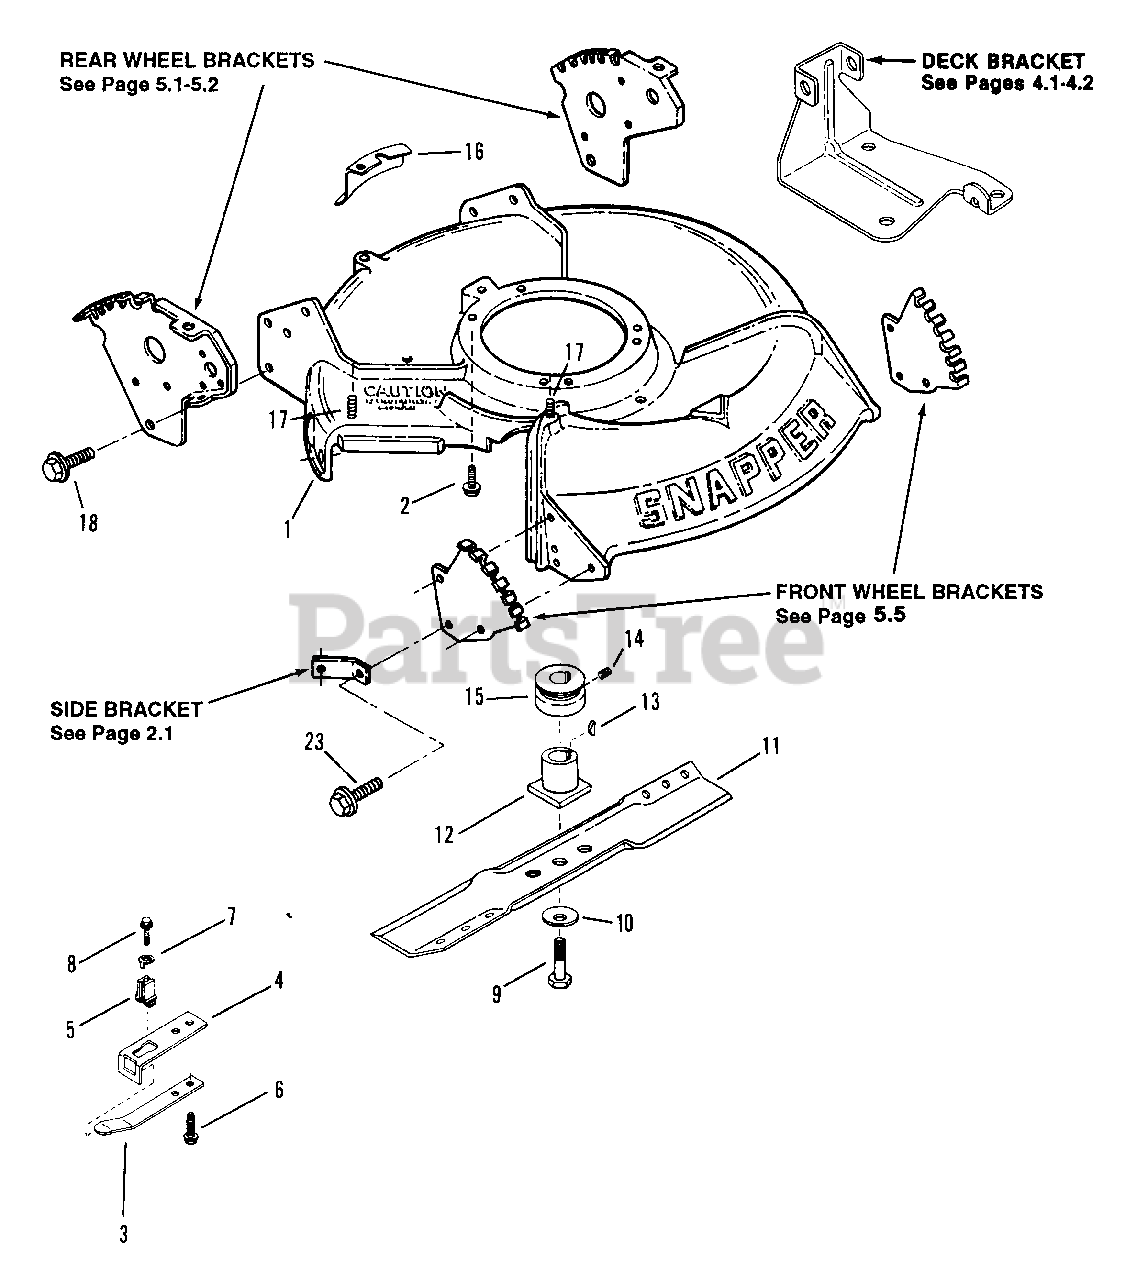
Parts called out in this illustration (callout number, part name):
1	DECK, Mower
2	SCREW, 3/8-16 x 1" Self-Tapping (Engine Mounting)
3	SPRING, Wheel Bracket Type Interlock
4	BRACKET, Wheel Bracket Type Interlock
5	INSULATOR, Interlock
6	SCREW, 1/4-20 x 1/2" Self-Tapping
7	WASHER, #8 Tab Internal Tooth Lock
8	SCREW, #8-18 x 3/4" Hex Head Machine
9	SCREW, 3/8-24 x 2" Hex Head Cap (Gr.5)
10	WASHER, Cone
11	BLADE, Cutter
12	HUB, Blade Drive (25mm Dia. I.D.)
13	KEY, Woodruff
14	SCREW, 5/16-18 x 5/16" Hex Socket Set
15	PULLEY, Engine
16	SHIELD, Belt Opening Cover
17	STUD, 5/16-18 x 1-1/2 Self-Tapping
18	SCREW, 5/16-18 x 5/8" Self-Tapping
